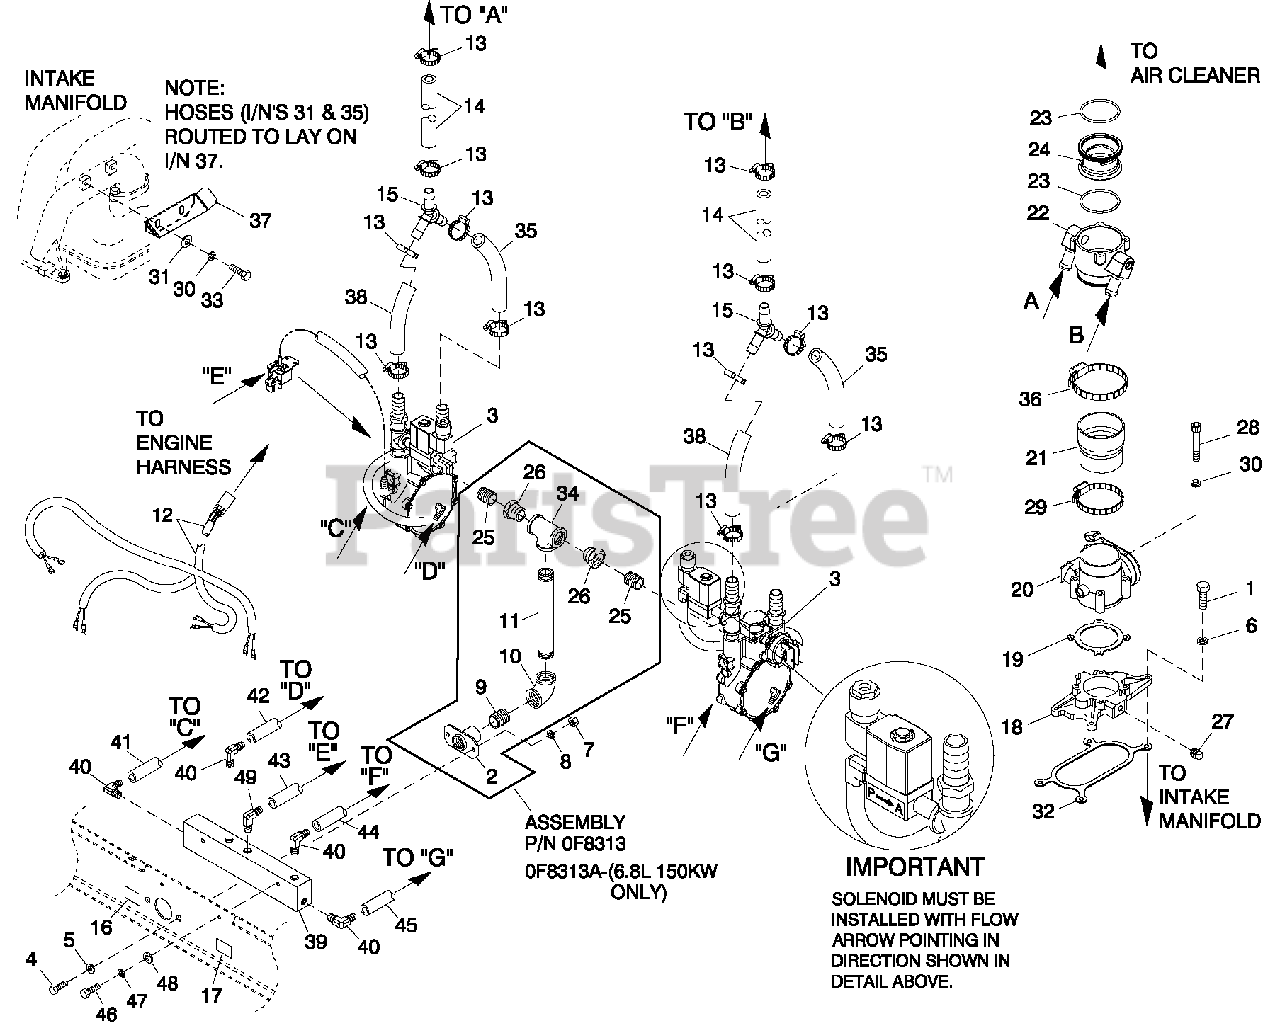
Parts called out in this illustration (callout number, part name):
1	SCREW HHC 5/16-18 X 1-1/4 G5
2	SUPPORT NAT GAS SOLENOID
3	REG 6.8L CPL 130 KW N/G EMISS
4	SCREW HHC M12-1.75 X 20 G8.8
5	WASHER FLAT 1/2 ZINC
6	WASHER LOCK M8-5/16
7	NUT HEX M12-1.75 G8 YEL CHR
8	WASHER LOCK 1/2
9	NIPPLE CLOSE 1.25 NPT X 1.625
10	ELBOW 90D1-1/4 NPT
11	NIPPLE PIPE 1-1/4 NPT X 3 (130 KW)
12	HARNESS, FUEL JUMPER DUAL REG
13	CLAMP HOSE #8 .53-1.00
14	HOSE 3/4 ID SAE-30R2 (42" LG)
15	Y CONNECTOR 500 SERIES BARBS
16	DECAL INLET PRESSURE
17	DECAL FUEL INLET NG
18	ASSY,ADAPTER,THROTTLE BODY
19	GASKET GOVERNOR ACTUATOR
20	ACTUATOR BOSCH 60 GOVERNOR
21	REDUCER 3.0" TO 2.75" TURBO
22	MIXER 40/60MM ACTUATOR ASSY
23	O-RING 2-3/4X3/32X2-15/16
24	VENTURI THROTTLE 44MM (130 KW)
25	NIPPLE CLOSE 3/4X1.375
26	BSHG RDCRHEX1-1/4-3/4
27	PLUG STD PIPE 1/4 STEEL SQ HD
28	SCREW SHC M6-1.0 X 50 C8.8
29	CLAMP HOSE #44 2.31-3.25
30	WASHER LOCK M6-1/4
31	WASHER FLAT M6
32	GASKET ADAPTER THROT BODY
33	SCREW HHC M6-1.0X 20 G8.8
34	PIPE TEE 1-1/4 NPT
35	HOSE 3/4 ID SAE-30R2 (12" LG)
36	CLAMP HOSE #52 2.81-3.75
37	BRACKET, HOSE RISER
38	HOSE 3/4 ID SAE-30R2 (9.5" LG)
39	MANIFOLD, EMISSIONS VACUUM
40	BARBED EL 90 3/16X1/8
41	HOSE VACUUM 5/32 (5" LG)
42	HOSE VACUUM 5/32 (7" LG)
43	HOSE VACUUM 5/32 (18" LG)
44	HOSE VACUUM 5/32 (6" LG)
45	HOSE VACUUM 5/32 (8" LG)
46	SCREW HHC M6-1.0X 25 G8.8
47	WASHER LOCK M6-1/4
48	WASHER FLAT 1/4-M6 ZINC
49	BARBED EL W/VENT (.052")
